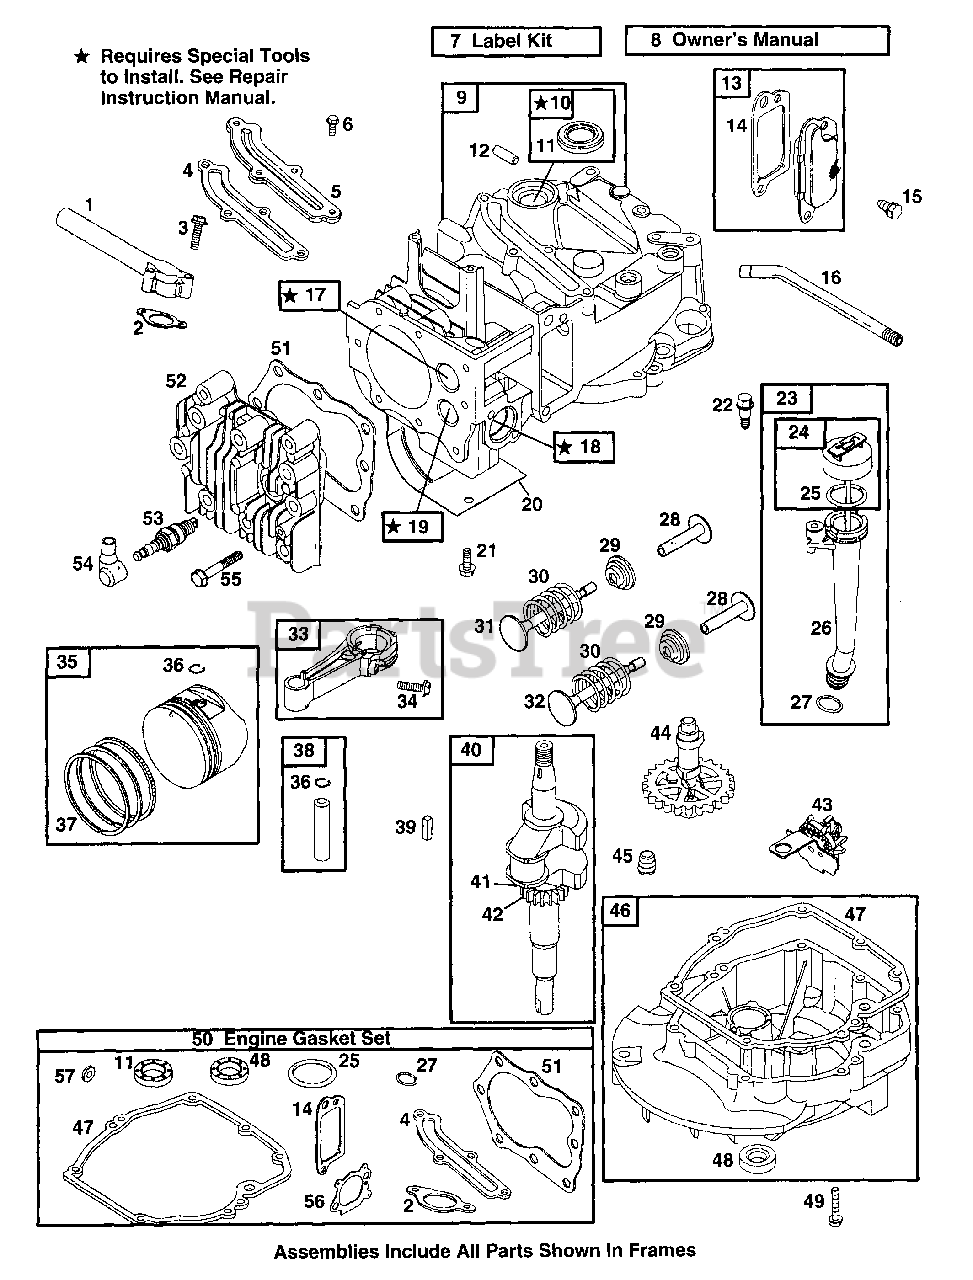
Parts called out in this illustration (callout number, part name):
1	Intake Manifold
2	Intake Gasket
3	Screw (Intake Manifold)
4	Breather Passage Gasket
5	Breather Passage Cover
6	Screw (Breather Passage Cover)
8	Owner's Manual
9	Cylinder Assembly
10	Bushing/Seal Kit
11	Oil Seal
12	Locating Pin
13	Breather Assembly
14	Breather Gasket
15	Screw (Breather Assembly)
16	Breather Tube
17	Valve Seat (Intake)
18	Guide Bushing (Intake Valve)
19	Valve Seat (Exhaust)
20	Cylinder Shield
21	Screw (Cylinder Shield)
22	Screw (Dipstick Tube)
23	Dipstick/Tube Assembly
24	Dipstick
25	Dipstick/Tube Seal
26	Oil Fill Tube
27	Dipstick Tube Seal
28	Valve Tappet
29	Valve Retainer
30	Valve Spring (Intake)
31	Intake Valve
32	Exhaust Valve
33	Connecting Rod
34	Screw (Connecting Rod)
35	Piston Assembly (Standard)
36	Piston Pin Lock
37	Ring Set (Standard)
38	Piston Pin
39	Flywheel Key
40	Crankshaft
41	Timing Gear
42	Timing Key
43	Governor/Oil Slinger
45	Oil Drain Plug
46	Engine Sump
47	Crankcase Gasket
48	Oil Seal
49	Screw (Engine Sump)
50	Engine Gasket Set
51	Cylinder Head Gasket
52	Cylinder Head
53	Spark Plug
54	Sparkplug Boot
55	Screw (Cylinder Head)
56	Air Cleaner Gasket
57	Spacer
